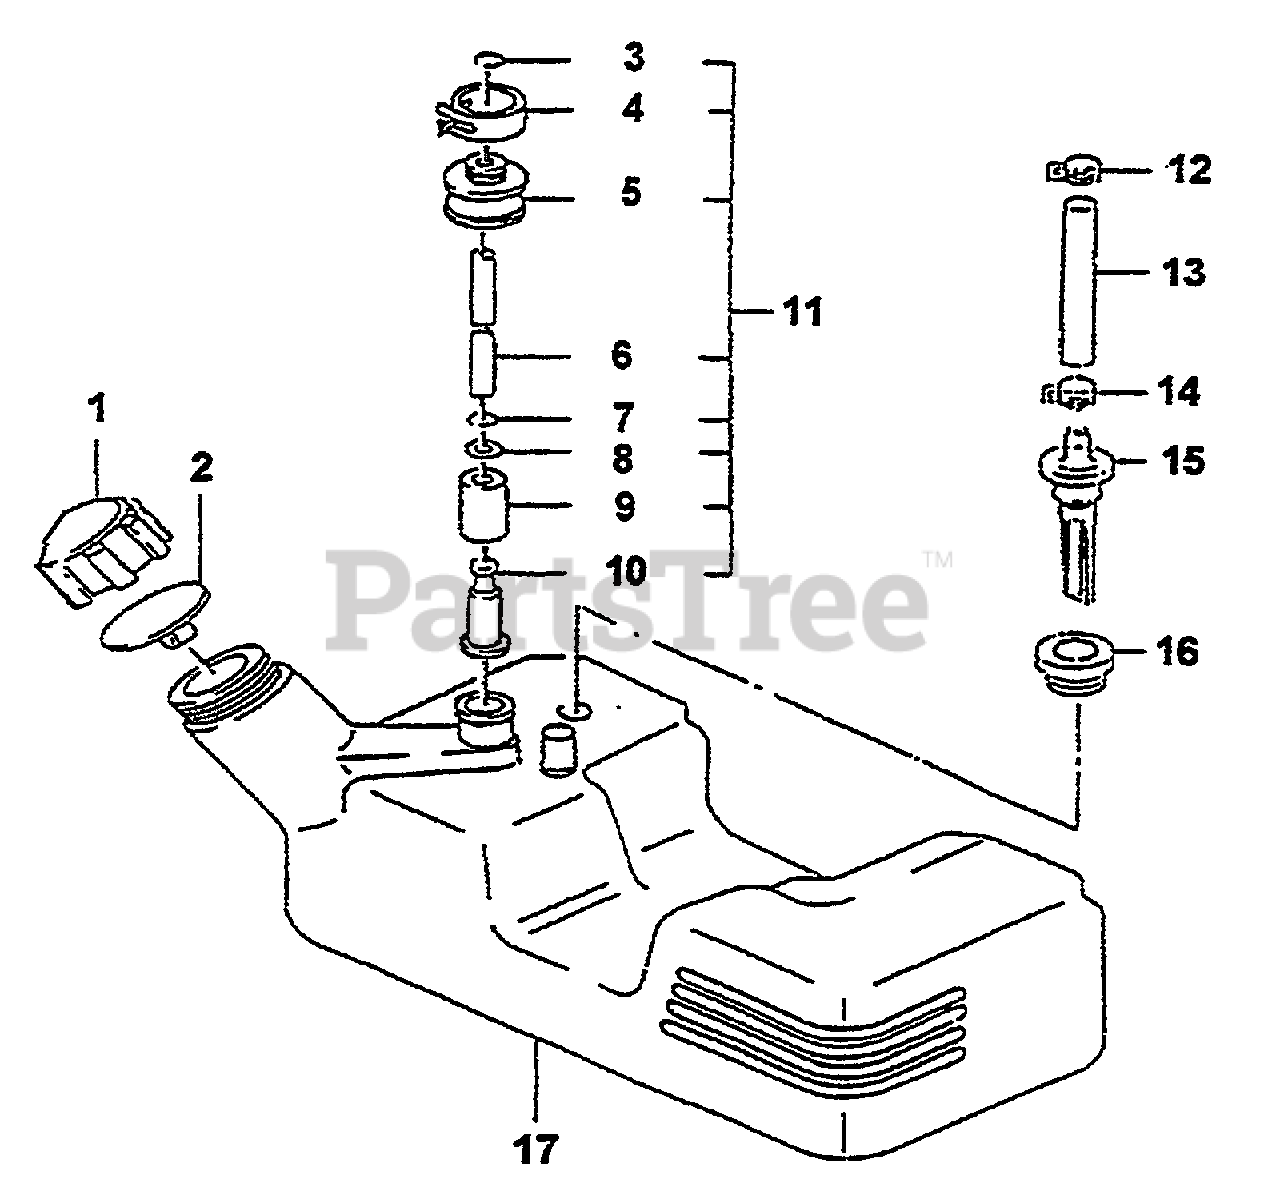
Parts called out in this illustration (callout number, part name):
6	FUEL TUBE
9	FUEL FILTER
11	FUEL FILTER ASSY
15	FUEL FILTER
17	FUEL TANK ASSY
